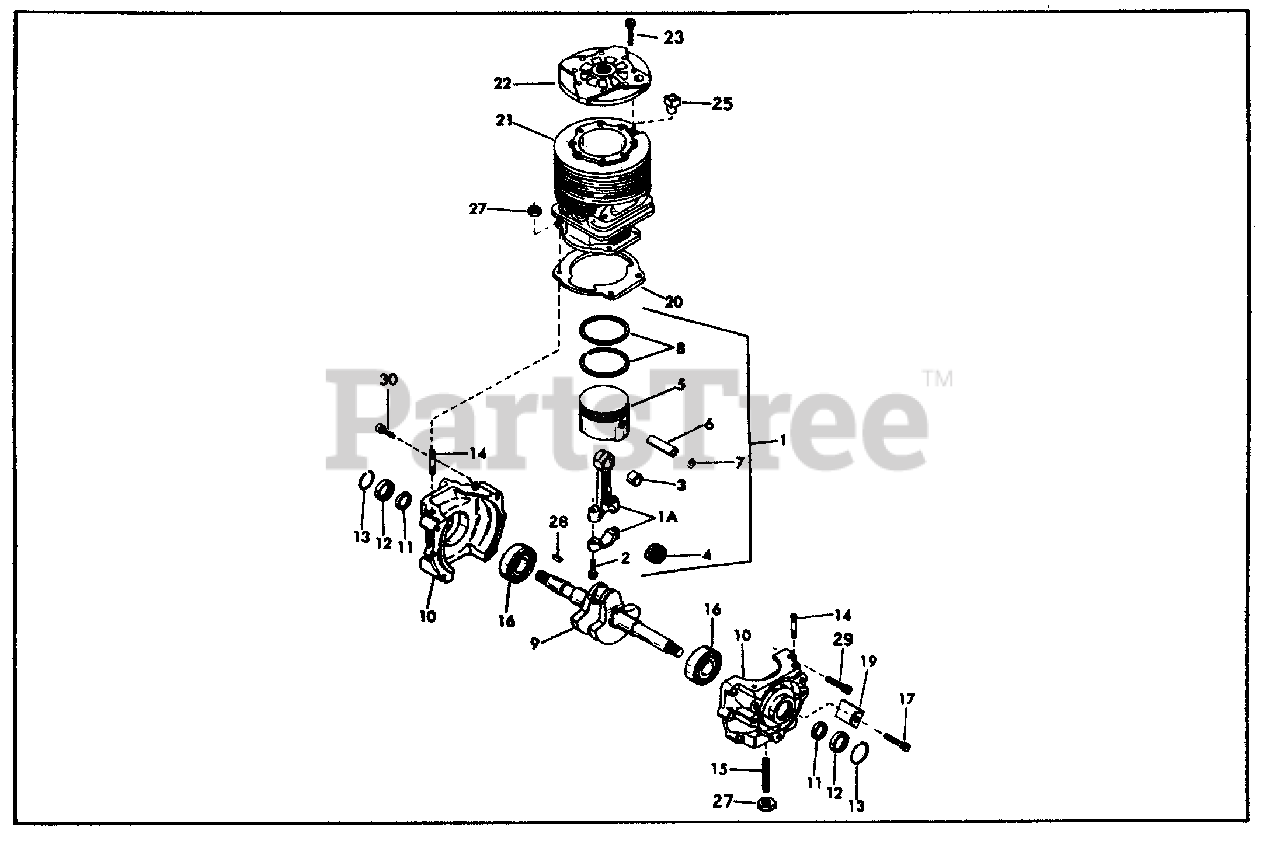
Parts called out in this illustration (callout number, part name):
1	"Cylinder (Incl. 2, 3 & 4) 2-5/16" Bo re
2	Dowel Pin
3	Oil Drain Plug (Sq. hd., 1/4-18)
4	Seal, Oil
5	Intake Valve (Std.) (Incl. 151)
5	Exhaust Valve (1/32" OS) (Incl. 151)
6	Exhaust Valve (Std.) (Incl. 151)
6	Exhaust Valve (1/32" OS) (Incl. 151)
7	Cap, Upper valve spring
8	Spring, Valve
9	Cap, Lower valve spring
9A	Cap, Lower valve spring
10	Pin, Valve spring retaining
11	Crankshaft (Incl. 24)
11	Crankshaft
12	Pin, Crankshaft gear only)
13	Crankshaft Gear Early production onl y
14	Piston Ass'y (Std.)(Incl. 14A,15,16) 2-5/16"
14	Piston Ass'y (.010 OS) Incl. 14A, 15 & 16
14	Piston Ass'y (.020 OS) Incl. 14A, 15 & 16
14A	Piston & Pin Ass'y. (Std.)(Incl. 16) 2-5/16"
14A	Piston & Pin Ass'y. (.010" OS) Incl. 16
14A	Piston & Pin Ass'y. (.020" OS) Incl. 16
15	Ring Set (Std.) (2-5/16" Bore)
15	Ring Set (.010" OS)
15	Ring Set (.020" OS)
16	Piston Pin Retaining Ring
17	Connecting Rod (Incl. 18 & 19)
18	Bolt, Connecting rod Late Production
18A	Bolt, Connecting rod Early Productio n
19	Oil Dipper
20	Nut, Lock (Used on Early Production)
21	Camshaft
22	Valve Lifter
23	Cover, Cylinder (Incl. 24, 25 & 50)
24	Oil Seal
24	Oil Seal equired)
24	Oil Seal (1-1/4", 1/4" thick) Use as required
25	Oil Fill Plug (Incl. 312) also availa ble in Packaged Part #740079
26	Cylinder Cover Gasket
28	Screw, 1/4-20 x 1" (Use as required)
28	Screw, 1/4-20 x 1-1/4" Use as requir ed
29	Flat Washer
30	Rod, Governor (Incl. 29) NOTE: To de termine which governor rod to use for Models SBH-7C,SBH-24C, SBH-47,C,D, a nd SBH-48,C,D, visibly compare rod fr om original engine. If rod from orig inal engine is not available for visi ble comparison, refer t
30A	Rod, Governor NOTE: To determine whi ch governor rod to use for Models SBH -7C,SBH-24C, SBH-47,C,D, and SBH-48,C ,D, visibly compare rod from original engine. If rod from original engine is not available for visible compari son, refer to parts list
31	Intake Pipe Gasket quired)
31	Flange Gasket (1/16" thick) Use as re quired
31	Intake Gasket (1/8" thick) Use as req uired
32	Cylinder Head Gasket
33	Screw, 8-32 x 5/16"
35	Bushing, Crankshaft (Use as required)
36	Cylinder Head Not included with bloc k
37	Decal, Instruction
38	Valve Cover Gasket
38	Gasket, Breather (Use as required)
43	Screw, 10-24 x 1/2"
45	Intake Pipe Gasket
46	Screw, 10-24 x 9/16"
48	Ball Bearing
49	Bearing Retainer
50	Shaft, Mechanical governor
51	Gear Assy., Governor (Incl. 54)
52	Retaining Ring
53	Spool, Governor
54	Washer, Flat
55	Oil Fill Plug Gasket
58A	Clamp, Governor lever
76	Decal, Name
